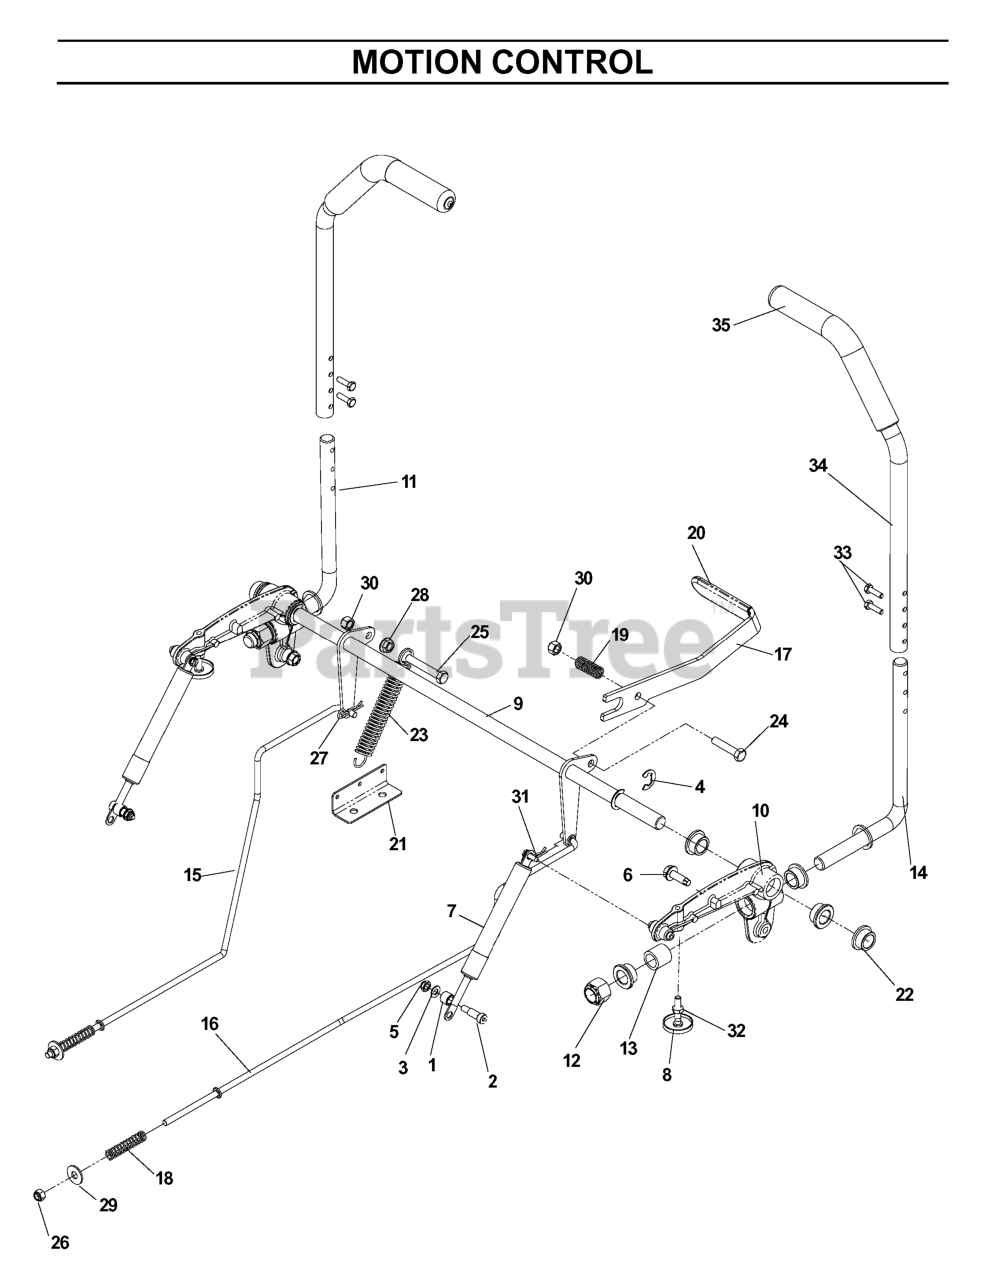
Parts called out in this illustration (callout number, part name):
2	SCREW, 5/16 X 5/8 SHOULDER
4	E-RING 5/8
5	JAM NUT 1/4C (2 2 PW01)
6	BOLT 5/16-18 X 1 1/4 TFS
8	POST, RETURN TO NEUTRAL
9	SHAFT, MOTION, BRAKE PLATED
10	MOTION CASTING
11	MOTION CONTROL ARM, WLDMNT LH
12	NUT 5/8-11 NYLOC
13	BUSHING ELASTOMER
14	MOTION CONTROL ARM, WLDMNT RH
15	BRAKE ROD FORMED RT
16	BRAKE ROD FORMED LT
17	BRAKE LEVER
19	BRAKE LEVER SPRING
20	BRAKE LEVER CAP
21	SPRING BRACKET
22	MOTION BUSHING
23	SPRING-TRANS
24	CAPSCREW 5/16 X 1/1/2 HEX HEAD
25	HCS 5/16-18X2
26	NUT.1/4-20.HEX.NYLOC.ZD
27	HAIRPIN #2
28	NUT 5/16C WHIZ
29	WASHER 5/16 FLAT
30	NUT 5/16 NYLOC
31	SCREW #10 X 1/2 SELF TAPPING
32	NUT 1/4-20 JAM
33	HCS 1/4-20X7/8 GR5
34	CONTROL LEVER
35	CONTROL LEVER CUSHION
